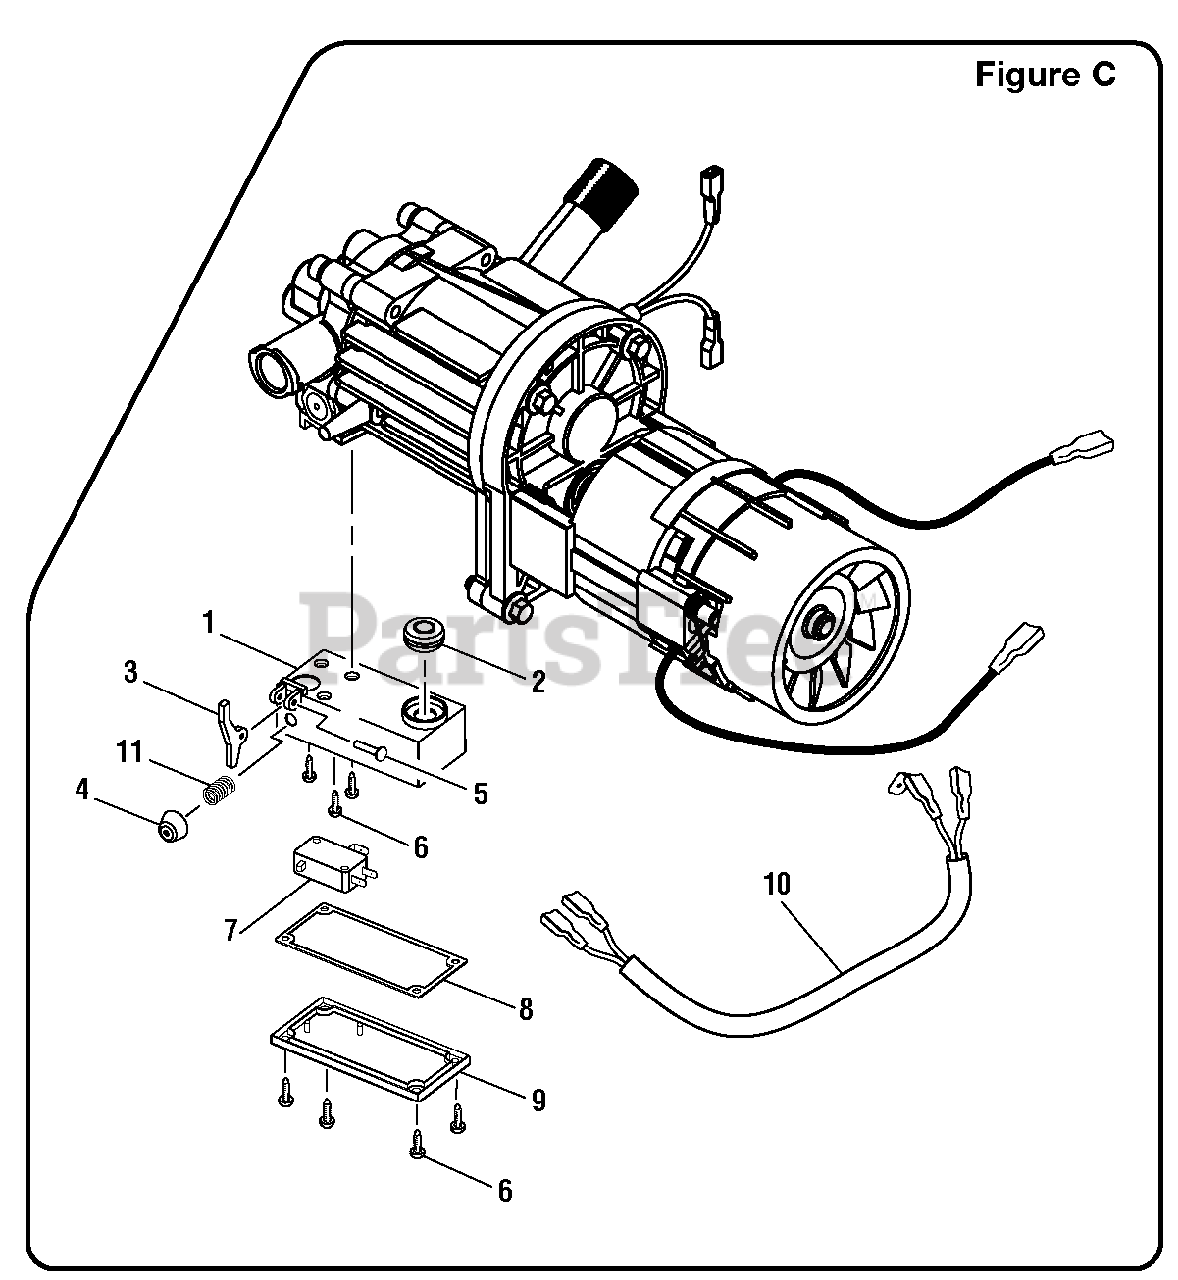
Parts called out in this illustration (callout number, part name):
1	Switch Box
3	Stop Switch Lever
4	Switch Box Seal
5	Stop Switch Lever Pin
6	Screw (2.9 x 10 mm)
7	Stop Switch
8	Switch Box Gasket
9	Switch Box Cover
10	Stop Switch Wiring Harness Assembly
11	Compression Spring
